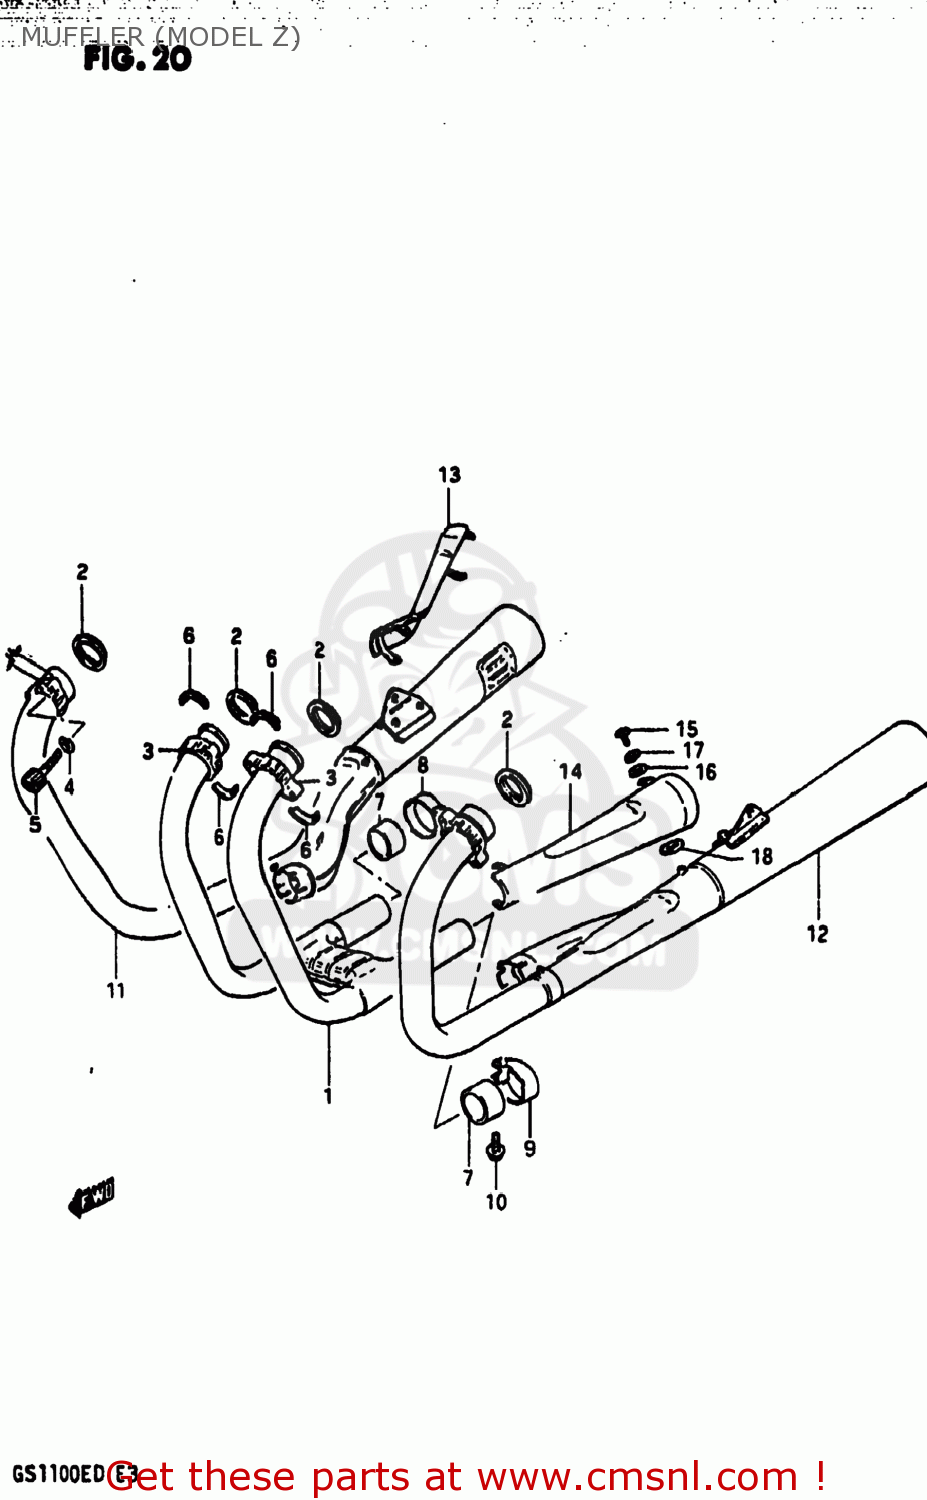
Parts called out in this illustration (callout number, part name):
1	PIPE,EXHAUST,CENTER
2	GASKET,EXHAUST PIPE (NAS)
3	CLAMP(H:21)
4	LOCK WASHER
5	BOLT
6	PLATE,EXHAUST
7	CONNECTOR,MUFFLER
8	CLAMP,MUFFLER CONNECTOR,R
9	CLAMP,MUFFLER CONNECTOR,L
10	BOLT
11	MUFFLER ASSEMBLY
12	MUFFLER ASSEMBLY
13	COVER,MUFFLER
14	COVER,MUFFLER
15	SCREW
16	WASHER
17	LOCK WASHER
18	GASKET 6.2X12X1.5 (MCA)
